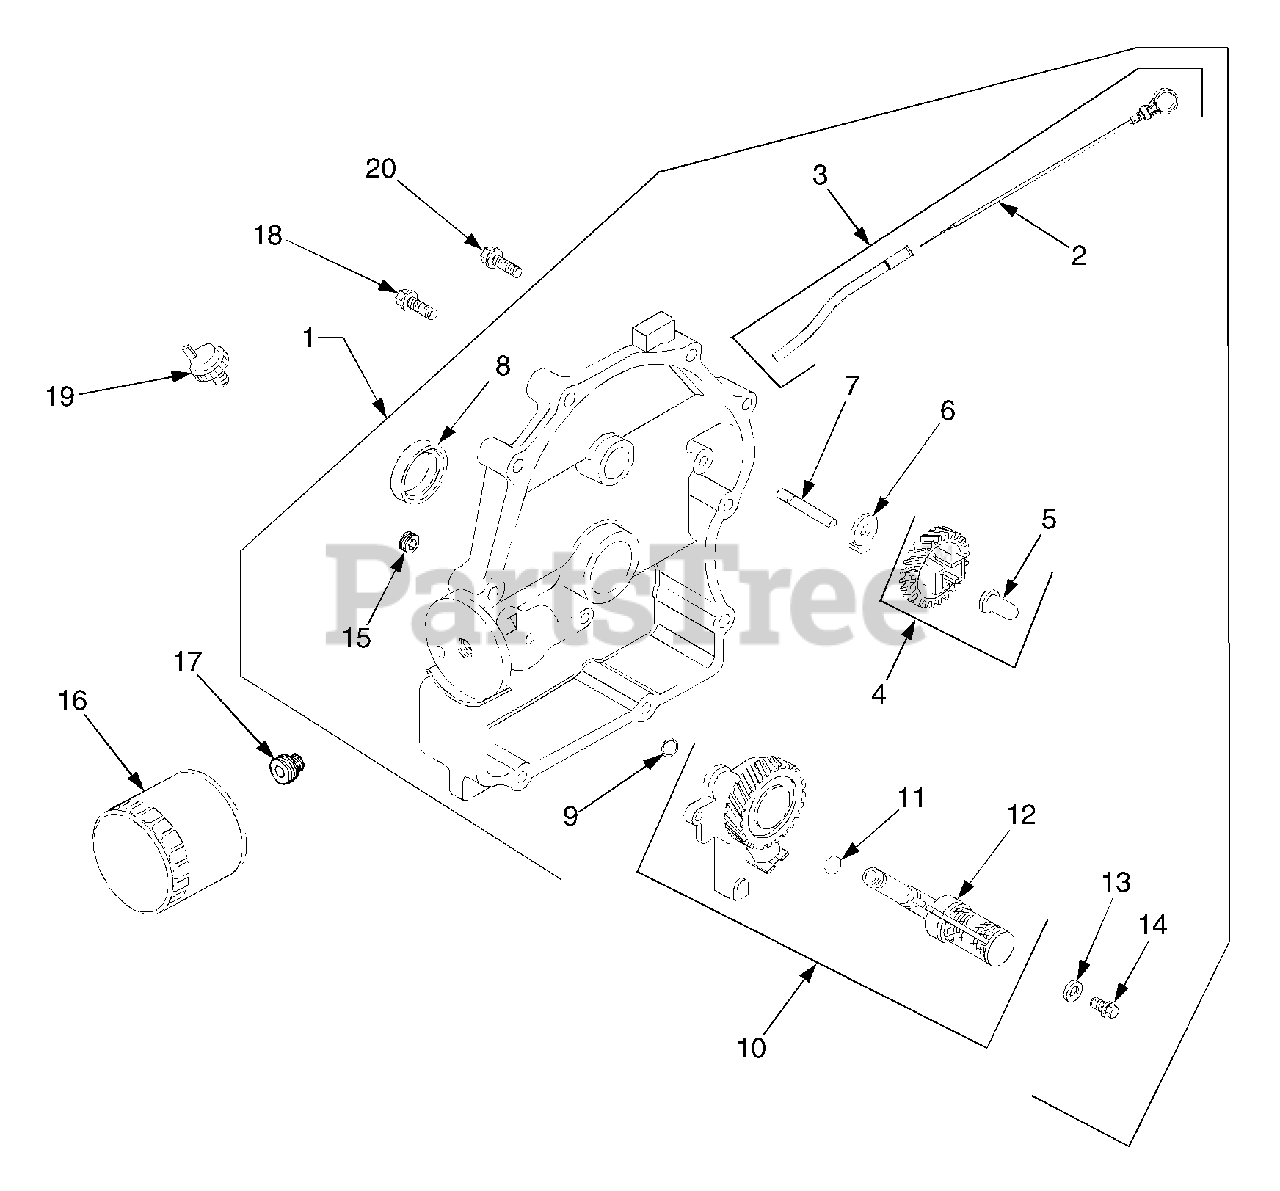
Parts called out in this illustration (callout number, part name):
1	Plate, Closure Assembly
3	Tube, Dipstick
4	Kit, Governor Gear
5	Pin, Governor Regulating
7	Shaft, Governor Gear
8	Seal, Oil (PTO End)
10	Oil Pump Assembly
11	O-Ring, Oil Pick-Up
12	Pick-Up, Oil
13	Washer, Plain
14	Screw, Hex Flange M6 x 1 x 25
15	Plug, Pipe 1/8"
16	Filter, Oil
17	Nipple, Oil Filter
18	Screw, Hex Flange M8 x 1.25 x 45
19	Switch, Pressure
20	Screw, Hex Flange M8 x 1.25 x 45
